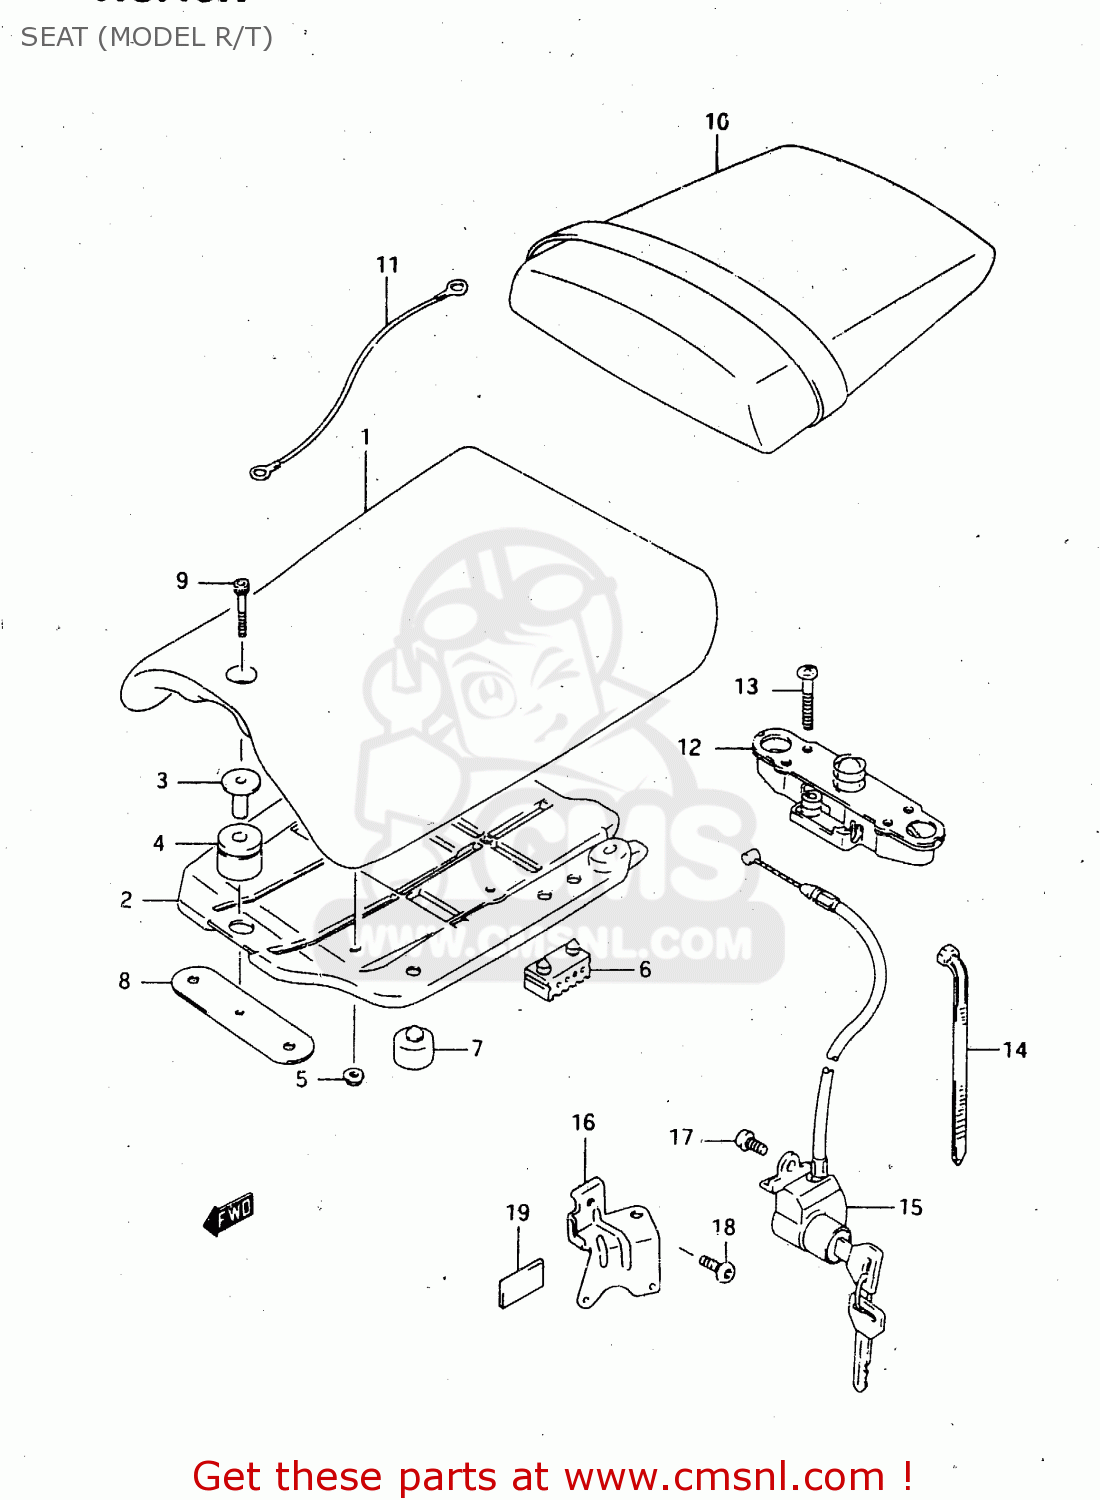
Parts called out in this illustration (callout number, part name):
1	SEAT ASSY
2	FRAME, SEAT BOTTOM
3	COLLAR,FR
4	CUSHION,SEAT
5	NUT
6	CUSHION,SEAT(40X20X15)
7	CUSHION
8	PLATE,SEAT FR
9	BOLT
10	SEAT ASSY,PILLION
11	CABLE,SEAT LOCK
12	LOCK ASSY,SEAT STRIKER
13	SCREW
14	CLAMP L:165
15	LOCK SET,SEAT
16	BRACKET, SEAT LOCK
17	SCREW(6X12)
18	SCREW
19	CUSHION,HEADLAMP COVER
